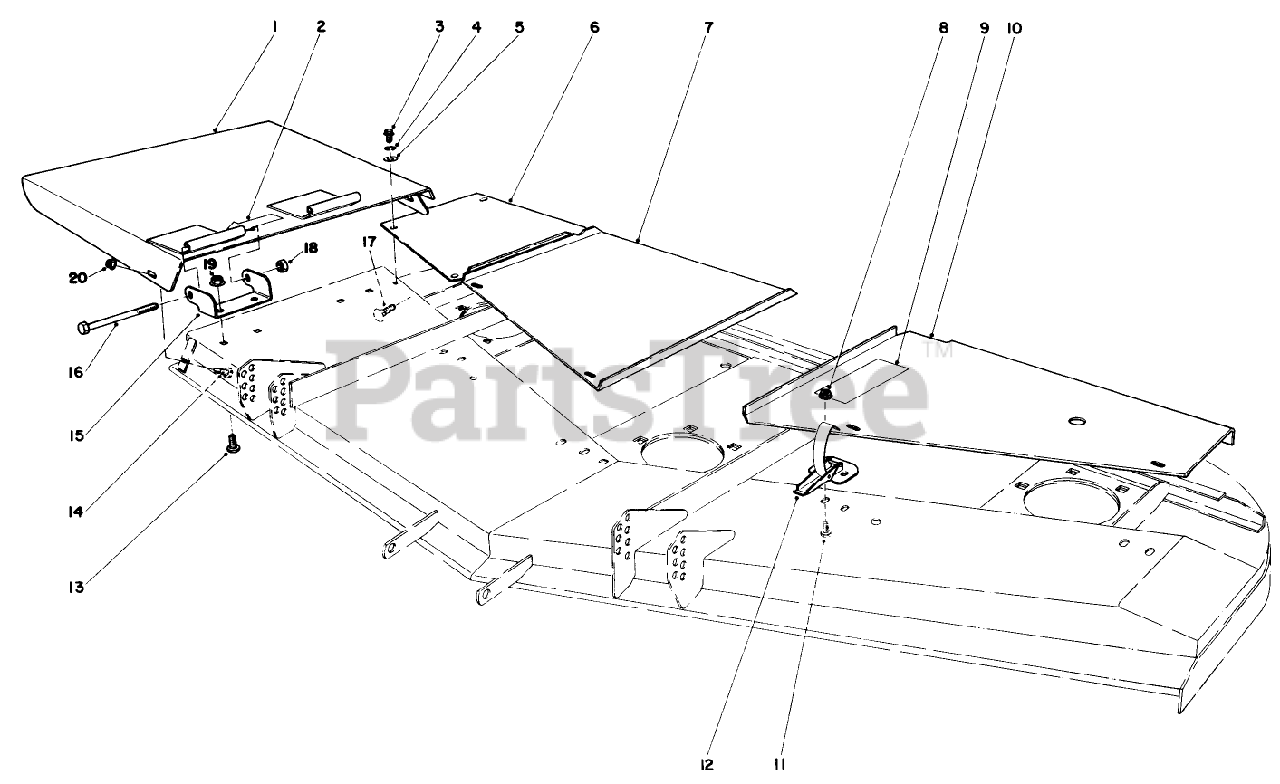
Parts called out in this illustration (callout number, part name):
3	SCREW THD 1/4 20 5/8
4	SCREW-HH
5	WASHER-FLAT
7	CTR DECK COVER *R
8	NUT-LOCK, FLANGE
11	SCREW-HWH
12	CLAMP-SLOTTED
13	SCREW-CARR
14	BOLT-CARR
16	SCREW-HH
18	NUT-HEX
19	NUT-HHF, WHIZ
20	NUT-HF
